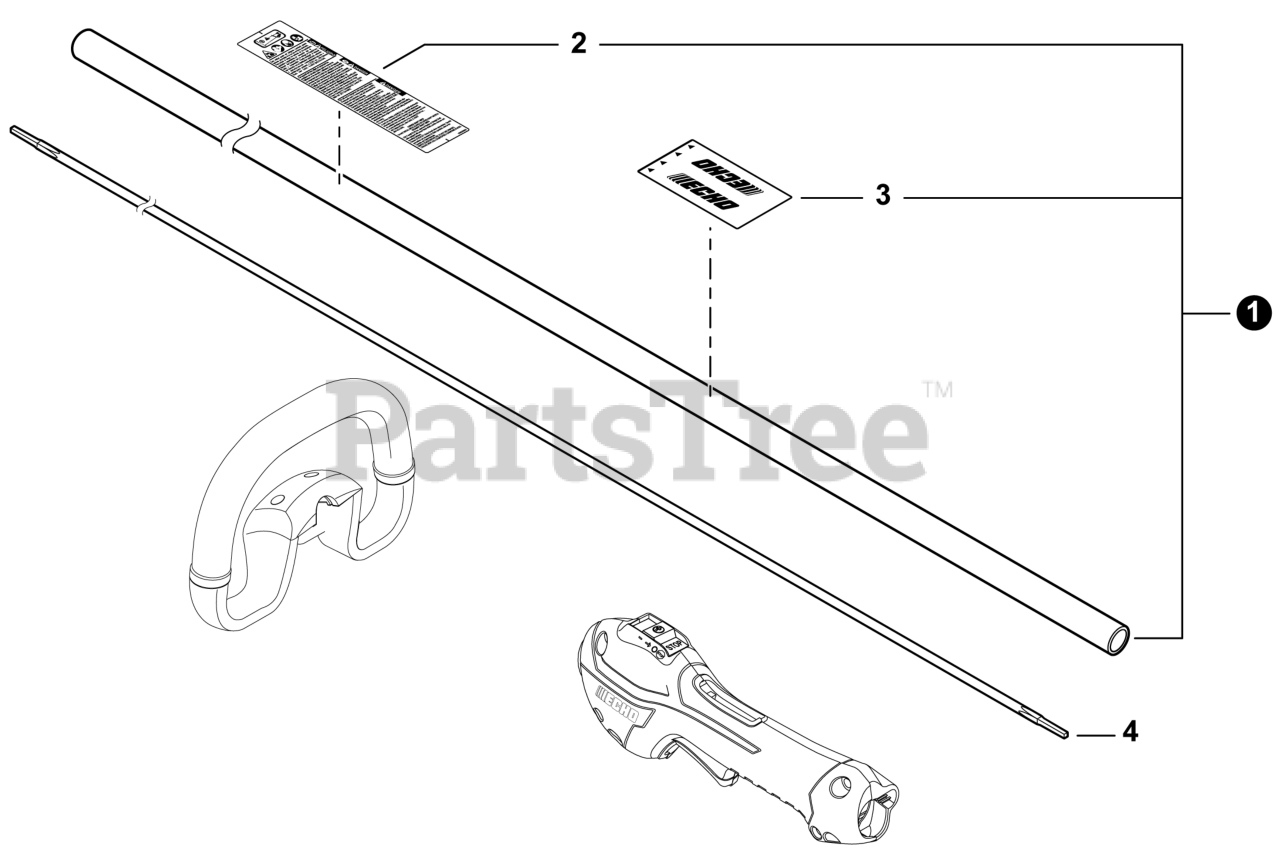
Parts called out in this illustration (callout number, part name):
1	MAIN PIPE ASSY
2	LABEL - CAUTION
3	LABEL - HANDLE LOCATION
4	DRIVESHAFT - FLEXIBLE
